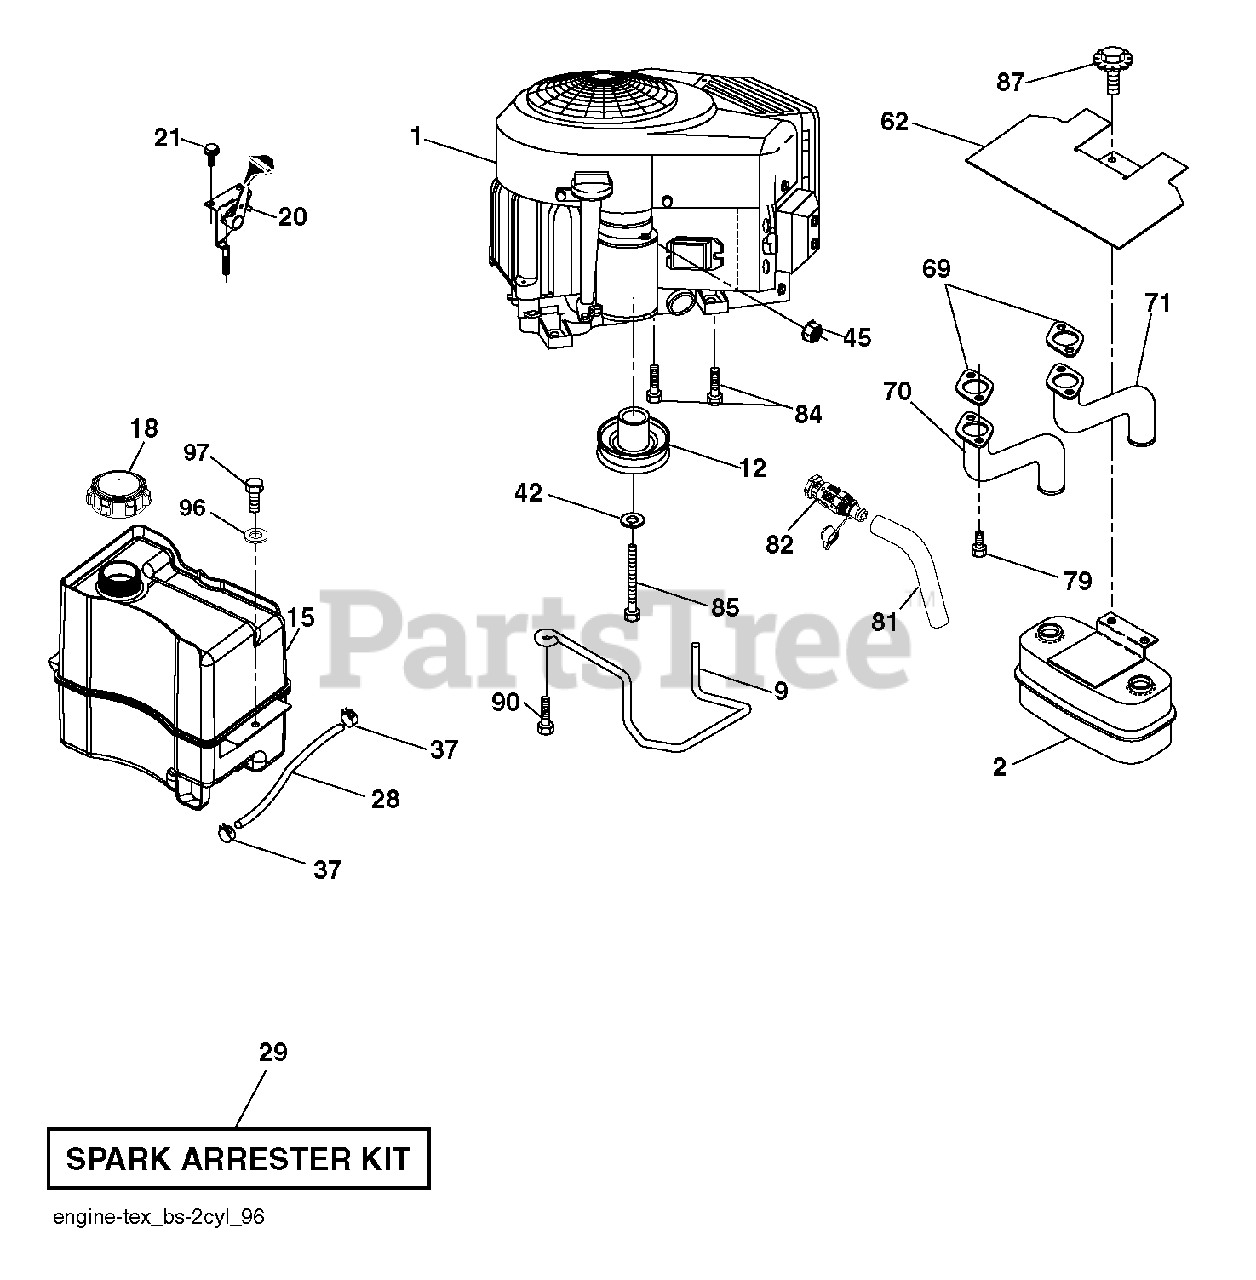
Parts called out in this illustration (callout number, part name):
2	MUFFLER.TWIN.CYL.LOW.TONE
9	KEEPER.BELT.ENGINE.4.2
12	PULLY ENGINE
15	TANK FUEL FRT 1.5 GAL
18	CAP ASM.FUEL.2.25"FR.
20	CONTROL.TH/CK.COBRA.B&S.TWN.
21	SCREW.#10 X 0.750.BOS THREAD
28	LINE.FUEL.20
29	ARRESTER SPARK (OPTIONAL)
37	HOSE CLAMP
42	LOCKWASHER
45	NUT
62	SHIELD.HEAT.MUFFLER
69	GASKET.MUFFLER
70	TUBE MANIFOLD LH
71	EXHAUST TUBE RH
79	SCREW.SOCKET.HEAD.5/16-18
81	TUBE, DRAIN OIL ASM.
82	VALUE.OIL.DRAIN
84	SCREW.3/8-16
85	BOLT HEX 7/16-20X4-1/4"
87	BOLT, 5/16-18 X 1 3/4
90	SCREW 3/8-16X1
97	SCREW HEXWSHR 1/4-20X3/4
